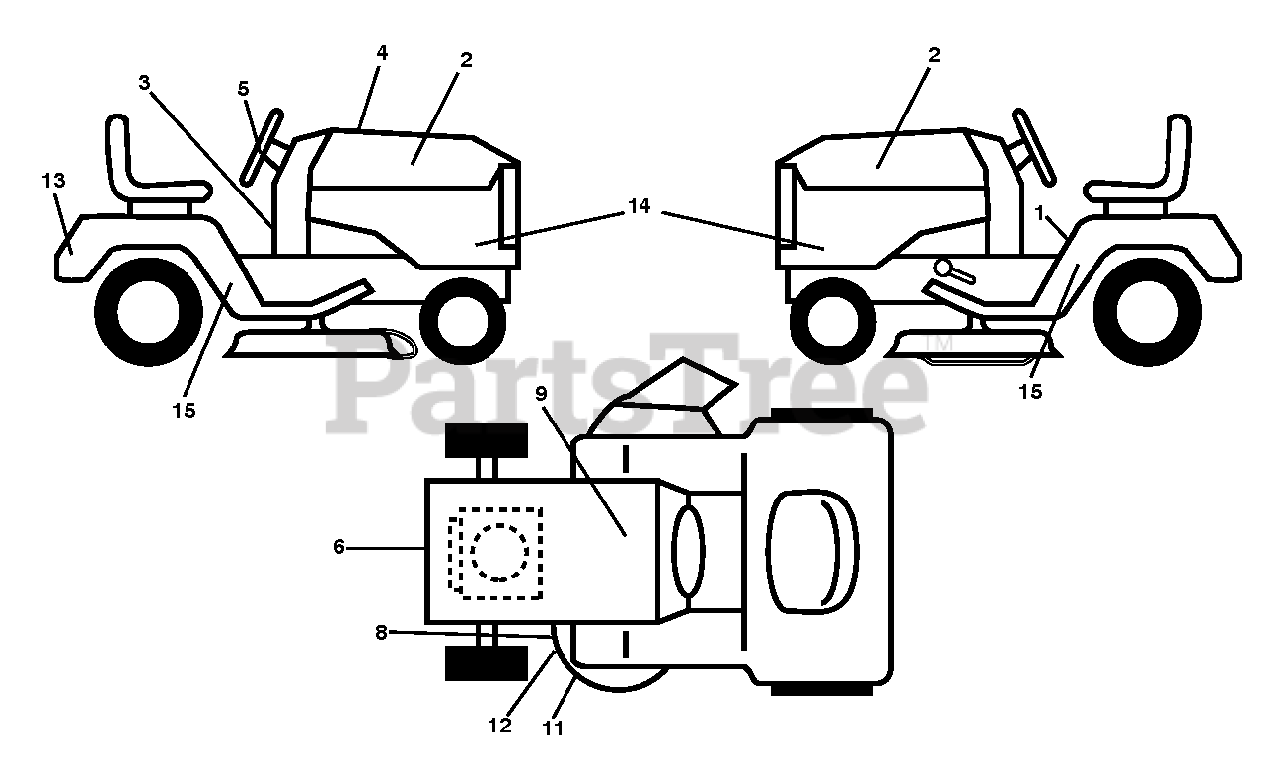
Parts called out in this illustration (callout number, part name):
1	DECAL.WARNING.2007.ENG/FR
2	DECAL.REAR.FNDR.LOGO.POULAN.PR
3	DCL.WARNING.SPARK.IGNITION.CA
5	DECAL.STEER.WHEEL.POULAN.PRO
6	DECAL.ENG.BS.26 HP.PROF.278955
8	DECAL.MOWER.SCH.48/54.PREM
9	DECAL BTRY SYMBOLS
11	DECAL.MOWER.CAUTION.TENSION.AR
12	DECAL.MOWER.WARN.KEEP.HAND.AWY
13	DECAL.REAR.FNDR.LOGO.POULAN.PR
